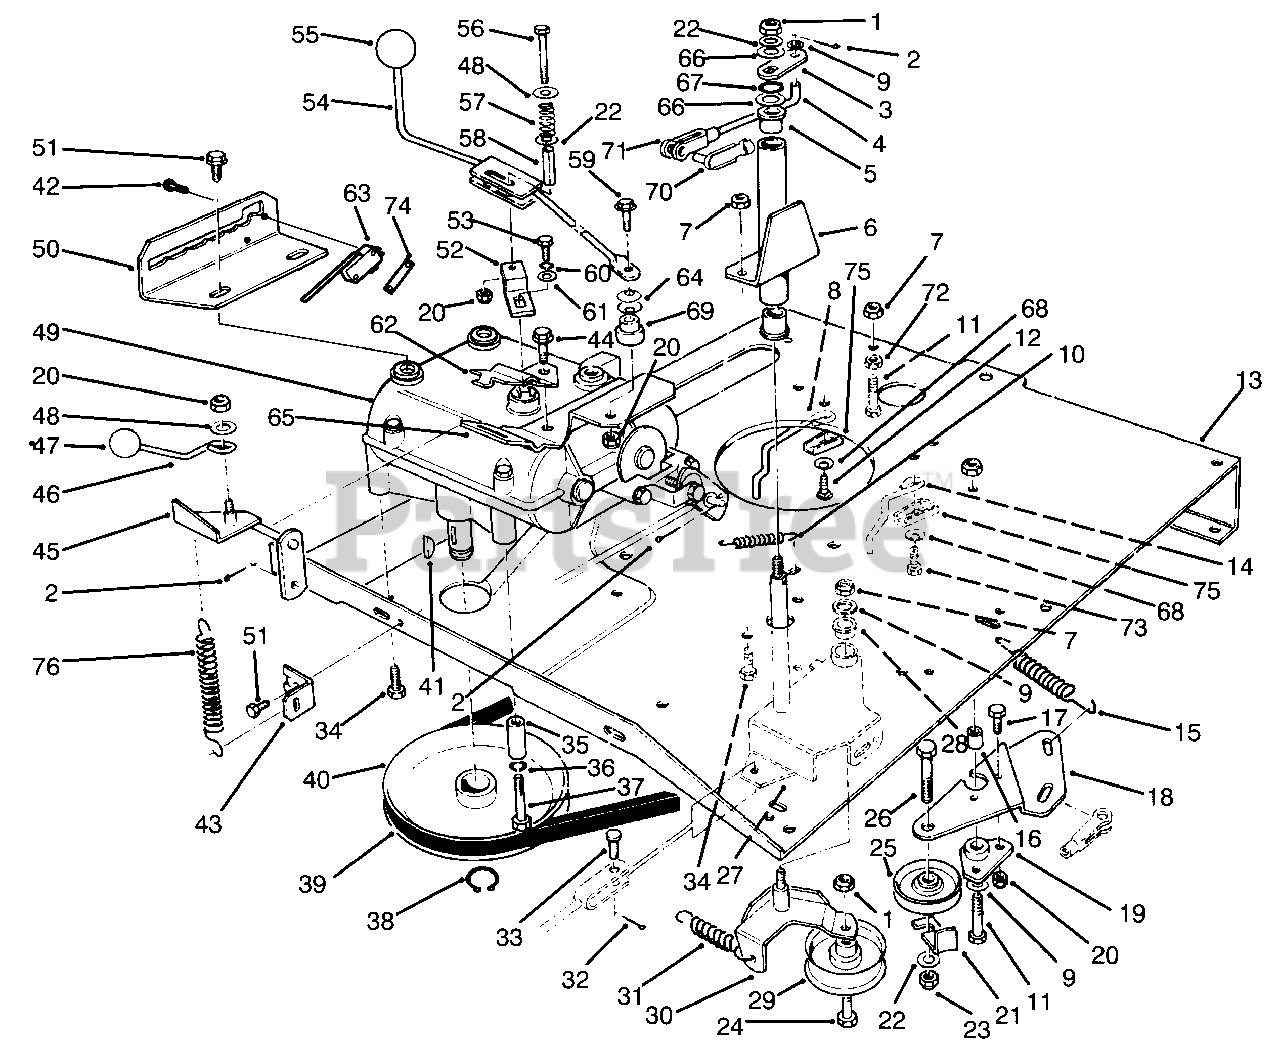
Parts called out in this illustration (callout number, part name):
1	Nut-Lock
2	Pin-Cotter
3	Flat-Deck Engage
4	Link-Deck Engage
5	Bushing
6	Tube W.A.-Pivot (Incl. Ref. #5)
7	Nut-Lock
8	Guide R.H.-Belt, Engine
9	Washer-Flat
10	Spring-Return, Brake
11	Screw-Cap Hex. Hd.
12	Bolt-Carriage
13	Plate-Engine
14	Guide L.H.-Belt, Engine
15	Spring-Traction
16	Spacer-Pivot
17	Screw-Cap Hex. Hd.
18	Plate-Mount, Idler
19	Mount-Pivot
20	Nut-Lock
21	Retainer-Belt
22	Washer-Flat
23	Nut-Lock
24	Screw-Cap Hex. Hd.
25	Pulley-Idler, Traction
26	Screw-Cap Hex. Hd.
27	Bracket-Arm, Idler (Incl. Ref. #28)
29	Pulley-Idler, Deck
30	Idler-Plate, Mount
32	Pin-Cotter
33	Pin-Clevis
34	Screw-Cap Hex. Hd.
35	Guide-Belt
36	Washer-Lock
37	Screw-Cap Hex. Hd.
38	Ring-Retaining
39	Belt-Traction
40	Pulley-Transmission
42	Screw-Tapping
43	Bracket-Mount, Spring
44	Screw-Hex. Hd. Tapping
45	Lever W.A.-Deck Engage
46	Handle-Deck Engage
48	Washer-Fender
49	Transmission
50	Gate-Shift
51	Screw-Wash. Hd., Tap.
52	Lever-Shift
53	Screw-Cap Hex. Hd.
54	Lever W.A.-Shift
56	Screw-Cap Hex. Hd.
59	Screw-Cap Hex. Hd.
60	Washer-Lock
61	Washer-Flat
62	Bracket-Engage, Deck
63	Switch-Micro
64	Washer-Belleville
65	Bracket-Mount, Shifter
66	Washer-Flat
67	Ring-Retaining
68	Washer-Belleville
69	Spacer-Pivot
70	Assembly-Pin, Clevis
72	Nut-Jam
73	Screw-Thread Forming
74	Nut-Double
75	Anchor-Guide, Belt
